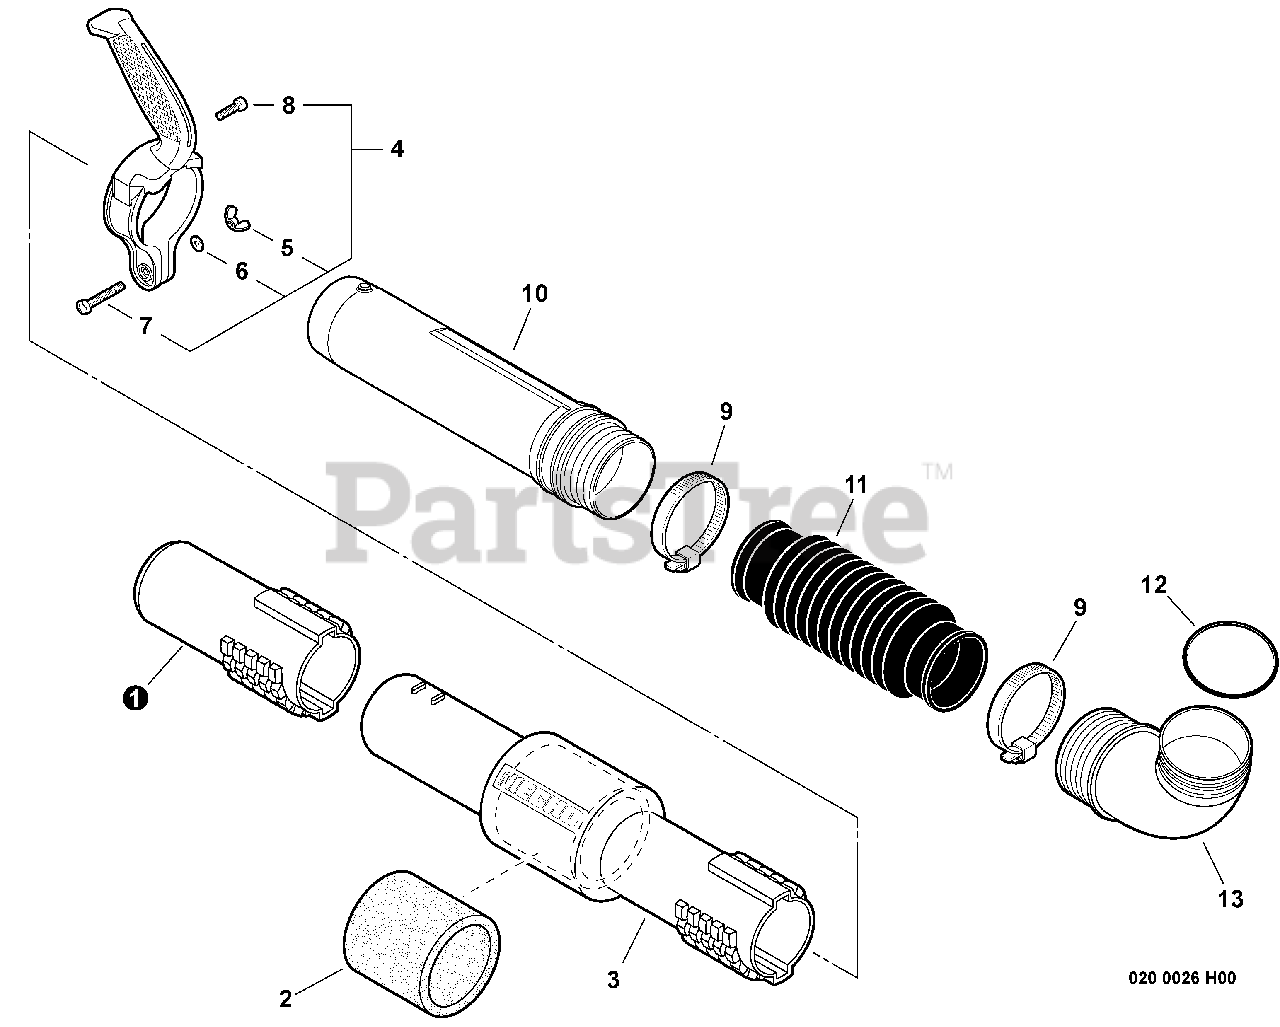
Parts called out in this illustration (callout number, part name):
1	TUBE, BLOWER - NOZZLE
2	PAD, FOAM
3	TUBE, BLOWER - STRAIGHT
4	BLOWER TUBE HANDLE ASSY
5	WINGNUT - 6
6	WASHER - 6
7	BOLT - 6X25
8	SCREW - 4X16 -- TAPPING
9	CLAMP, HOSE
10	TUBE, BLOWER - SWIVEL
11	TUBE, BLOWER - FLEXIBLE
13	TUBE, BLOWER - ELBOW
